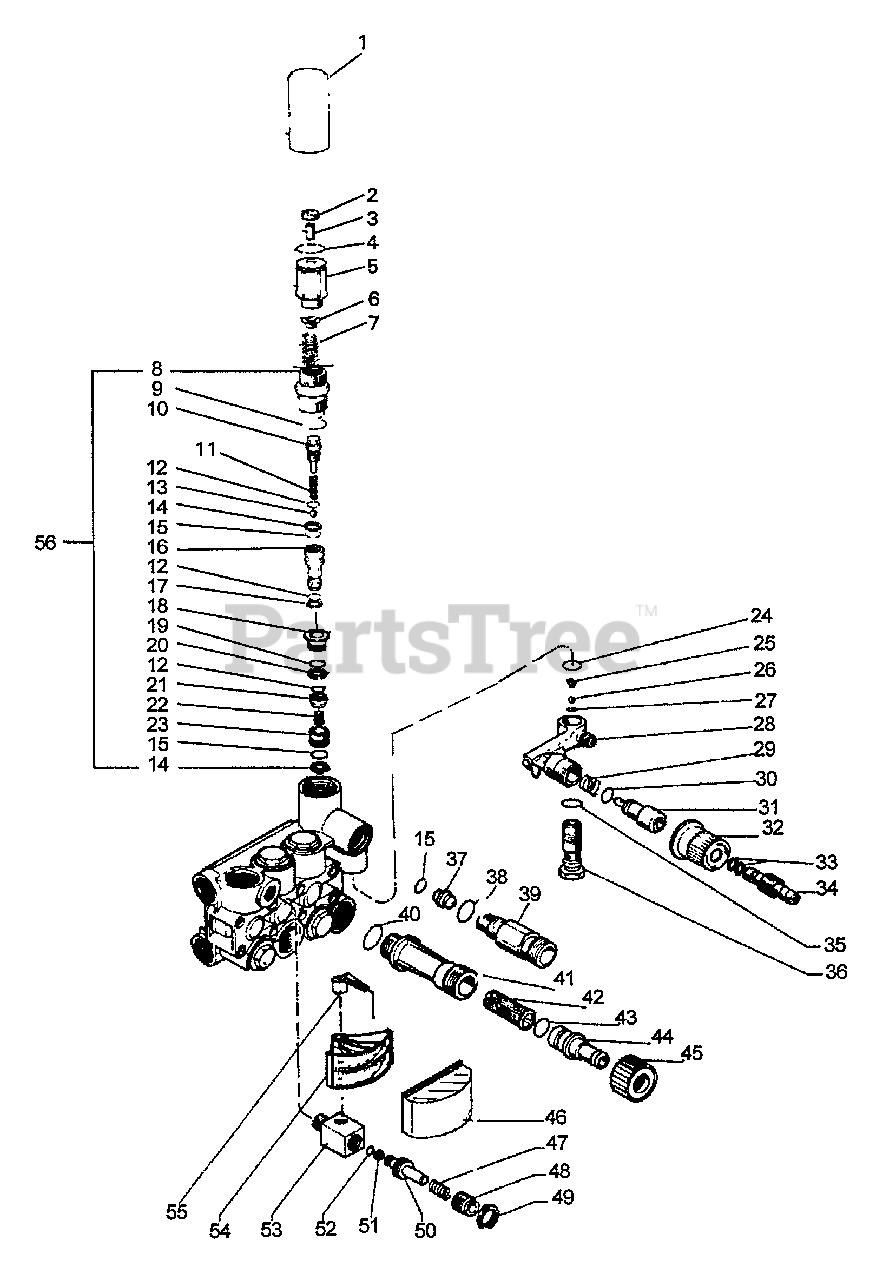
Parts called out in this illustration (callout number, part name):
1	KNOB, PRESSURE REGULATOR
2	NUT - 8
3	SCREW - 8X16
4	O-RING
5	SCREW, PRESSURE SET
6	PLATE, SPRING
7	SPRING
8	BUSHING, GUIDE
9	O-RING - .797 X.103
10	STOPPER, STROKE
11	SPRING
12	O-RING
13	BALL - 9/32"
14	RING, ANTI-EXTRUSION
15	O-RING
16	PISTON, CONTROL
17	RING, ANTI-EXTRUSION
18	GUIDE, VALVE
19	O-RING, .489 X.070
20	RING, ANTI-EXTRUSION
21	VALVE, BALL
22	SCREW - 5
23	SEAT, VALVE
24	O-RING
25	SPRING, TAPER
26	BALL
27	O-RING
28	BODY, INJECTOR
29	SPRING
30	O-RING
31	SHUTTER, INJECTOR
32	KNOB, CHEMICAL REGULATOR
33	O-RING
34	FITTING, HOSE BARB
35	O-RING
36	SEAT, CHEMICAL VALVE
37	NOZZLE
39	NIPPLE
41	NIPPLE
44	FITTING, HOSE, BARB
45	RINGNUT
46	COVER
47	SPRING
48	SCREW - 14X1
49	NUT - 14
50	PISTON
51	RING, BACK-UP
52	O-RING
53	BODY
54	DIAL
55	INDICATOR
56	VALVE KIT
